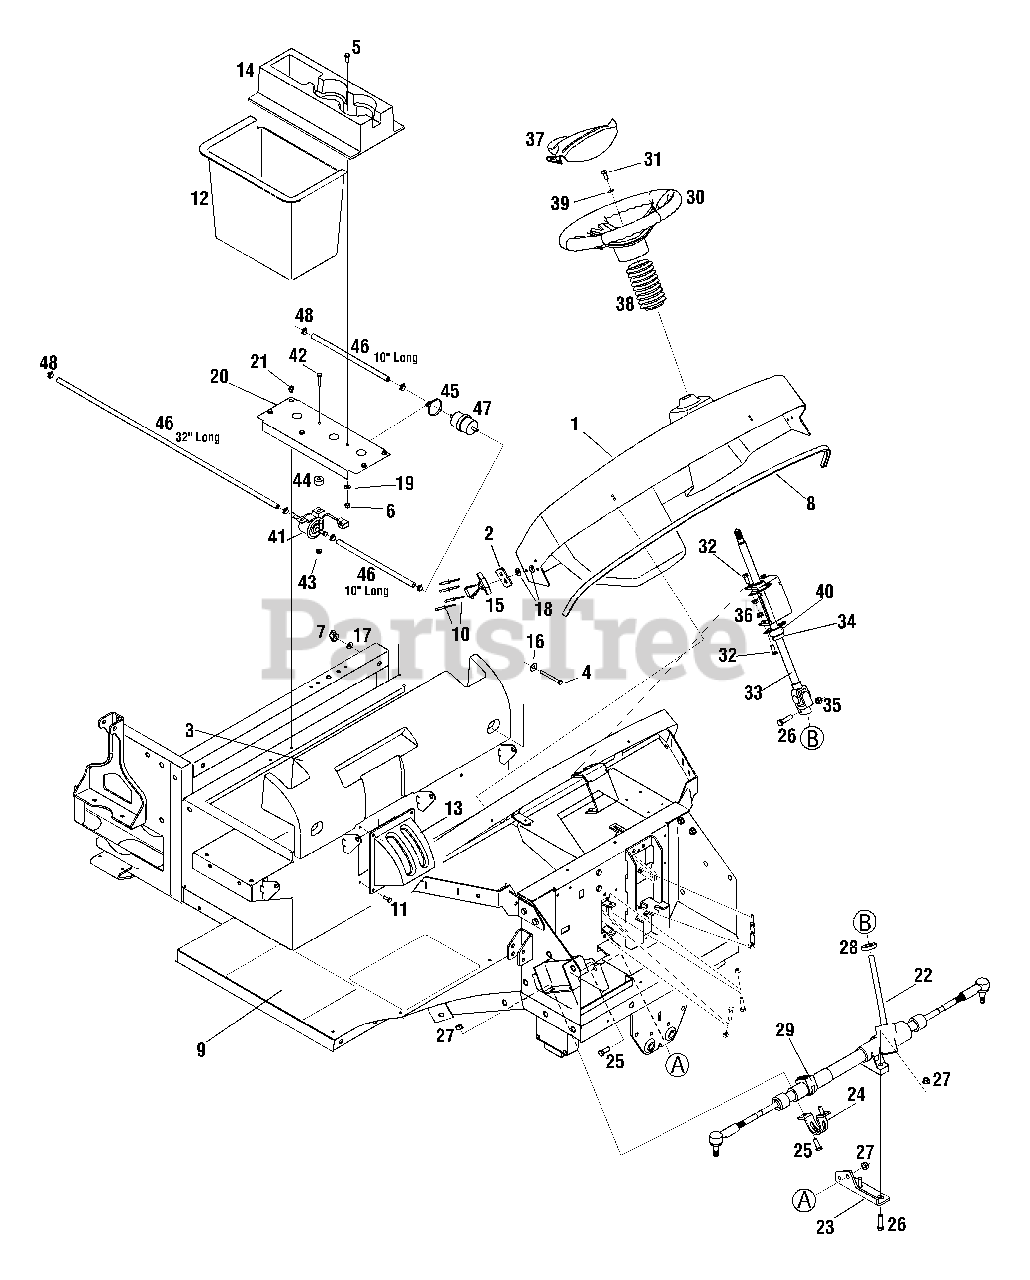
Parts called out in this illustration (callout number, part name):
1	Dash Assembly
2	Hood Mounting Plate
3	Panel, Airbox Cover
4	Hex Screw, 1/4-20 x 2.75
5	Hex Screw, 1/4-20 x.75, Gr5
6	Hex Lock Nut, Nylon, 1/4-20
7	Wing Nut, 1/4-20
8	Trim, Bulb Seal, 1/4
9	Foot Pad, Abrasive
10	Rivet, Pop,.187
11	Rivet, Pop,.188
12	Container, Bulkhead
13	Panel, Shift Cover
14	Console, Cup Holder
15	Handle, Latch
16	Flat Washer, 349 x.875 x.04
17	Washer, Flat,.28 x.74 x.063
18	Washer, Flat,.194 x.62 x.063
19	Washer, Flat,.25 x.630 x.0515
22	Gear Assembly, Steering
25	Hex Screw, 3/8-16, 1.00, Gr5
26	Hex Screw, 3/8-16, 1.50, Gr5
27	Nut, Flange Lock, 3/8-16
28	Grommet, Steering Shaft
29	Bushing, Rubber
30	Wheel, Steering
31	Hex Screw, 5/16-18,.75, Gr5, Patch
32	Hex Screw, 5/16-18, .75, Gr5
33	Shaft, Steering, 5/8 Spline
34	Collar, .75
35	Nut, Hex Lock Nylon, 3/8-16
36	Nut, Flange Lock, 5/16-18
37	Cover, Steering Wheel
38	Bellow, Steering, 4.75 Lg
39	Washer, Flat,.344 x.688 x.065
40	Bearing, Flange,.75 ID, Self-Aligning
41	Pump Assembly, Fuel
42	Hex Screw, 1/4-20 x 1.25
43	Flange Lock Nut, 1/4-20
44	Bushing,.96OD x.50
45	Cable Tie
46	Fuel Line Hose
47	Fuel Filter
48	Clamp, Hose
